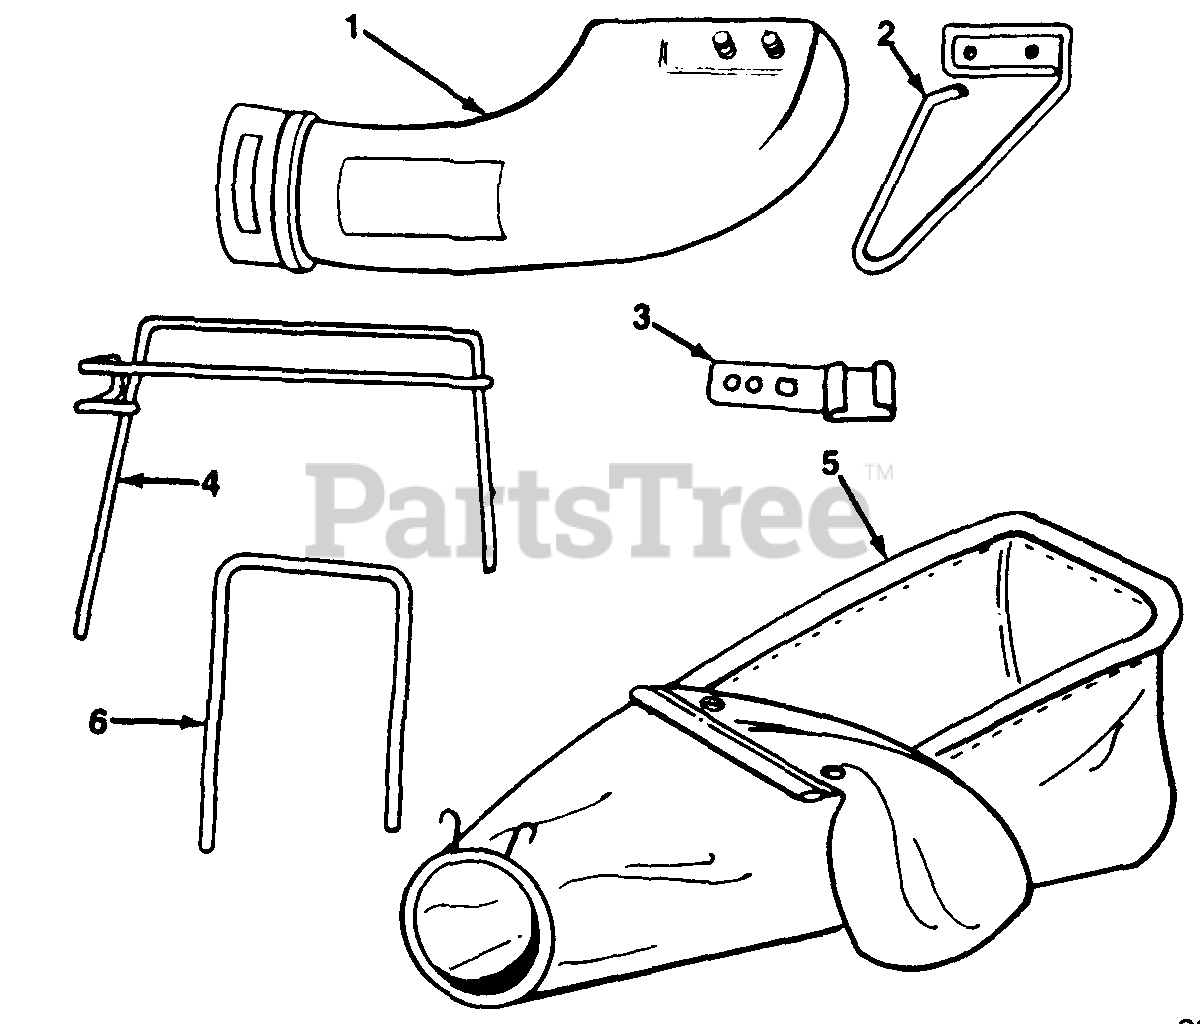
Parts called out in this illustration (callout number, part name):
1	Plastic Chute
2	Chute Mounting Bracket w/Wire
3	Handle Bracket
5	Bag w/Clamp Ring
6	Upper Support Tube
